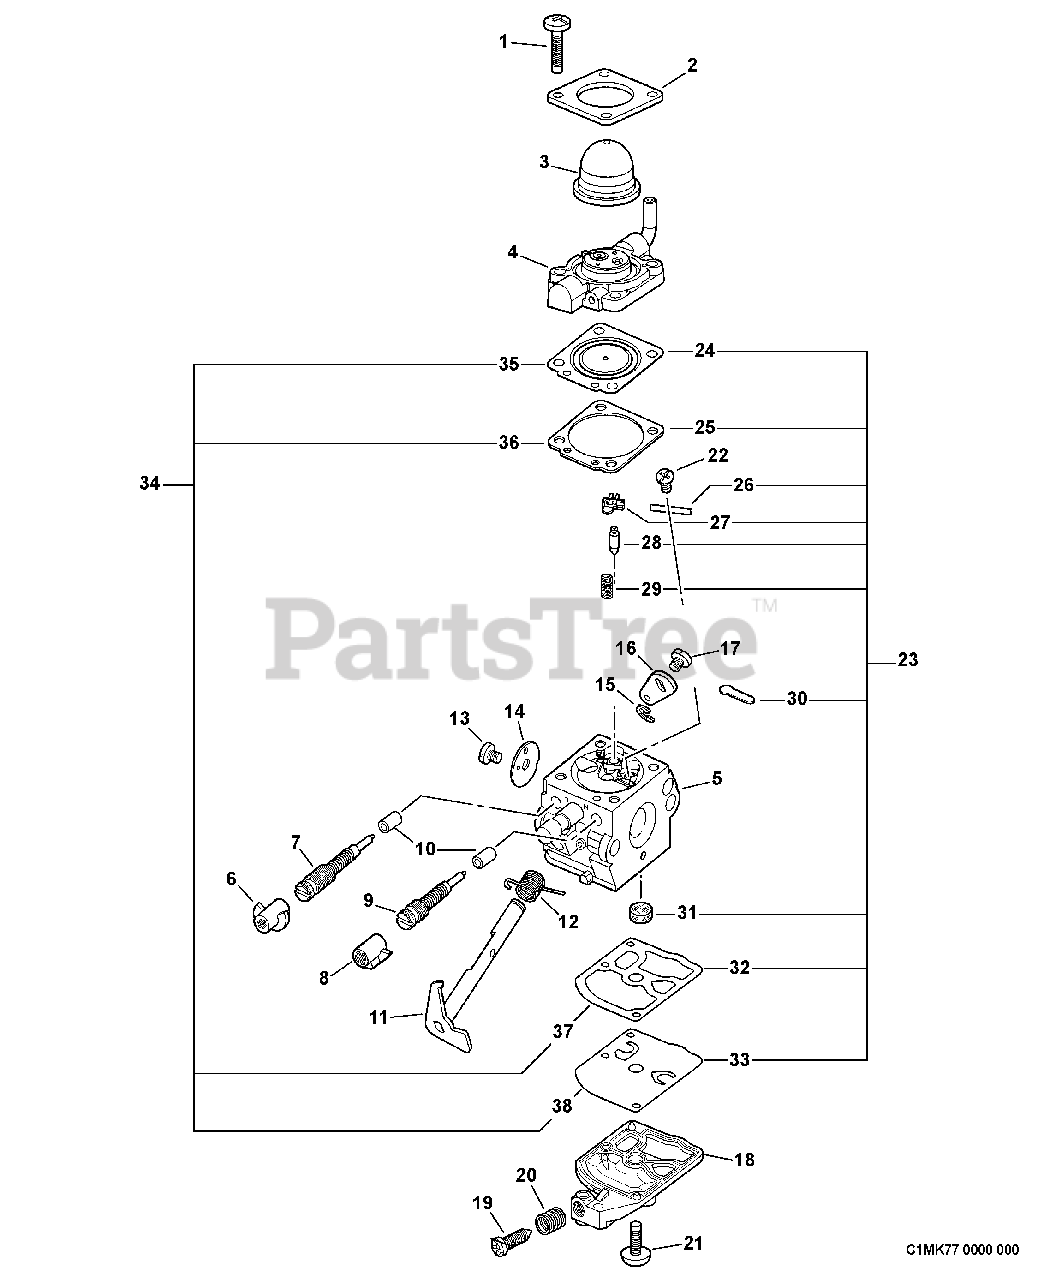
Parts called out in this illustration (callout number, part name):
1	SCREW, RETAINER
2	RETAINER, PURGE BULB
3	BULB, PURGE
4	BASE, PURGE
5	BODY, CARBURETOR
6	CAP, LIMITER
7	NEEDLE - LOW SPEED
8	CAP, LIMITER
9	NEEDLE - HIGH SPEED
10	RETAINER
11	SHAFT, THROTTLE
12	SPRING, TRIGGER
14	VALVE, THROTTLE
15	RING, RETAINING
16	LEVER, THROTTLE
18	COVER, FUEL PUMP
19	SCREW, IDLE ADJUST
20	SPRING, IDLE ADJUST
21	SCREW, PUMP COVER
22	SCREW, METERING LEVER PIN
23	REPAIR KIT
24	DIAPHRAGM, METERING
25	GASKET, DIAPHRAGM
26	PIN, METERING LEVER
27	LEVER, METERING
28	VALVE, INLET NEEDLE
29	SPRING, METERING LEVER
30	PLUG, WELCH
31	STRAINER
32	DIAPHRAGM, PUMP
33	GASKET, PUMP
34	DIAPHRAGM/GASKET KIT
35	DIAPHRAGM, METERING
36	GASKET, DIAPHRAGM
37	DIAPHRAGM, PUMP
38	GASKET, PUMP
